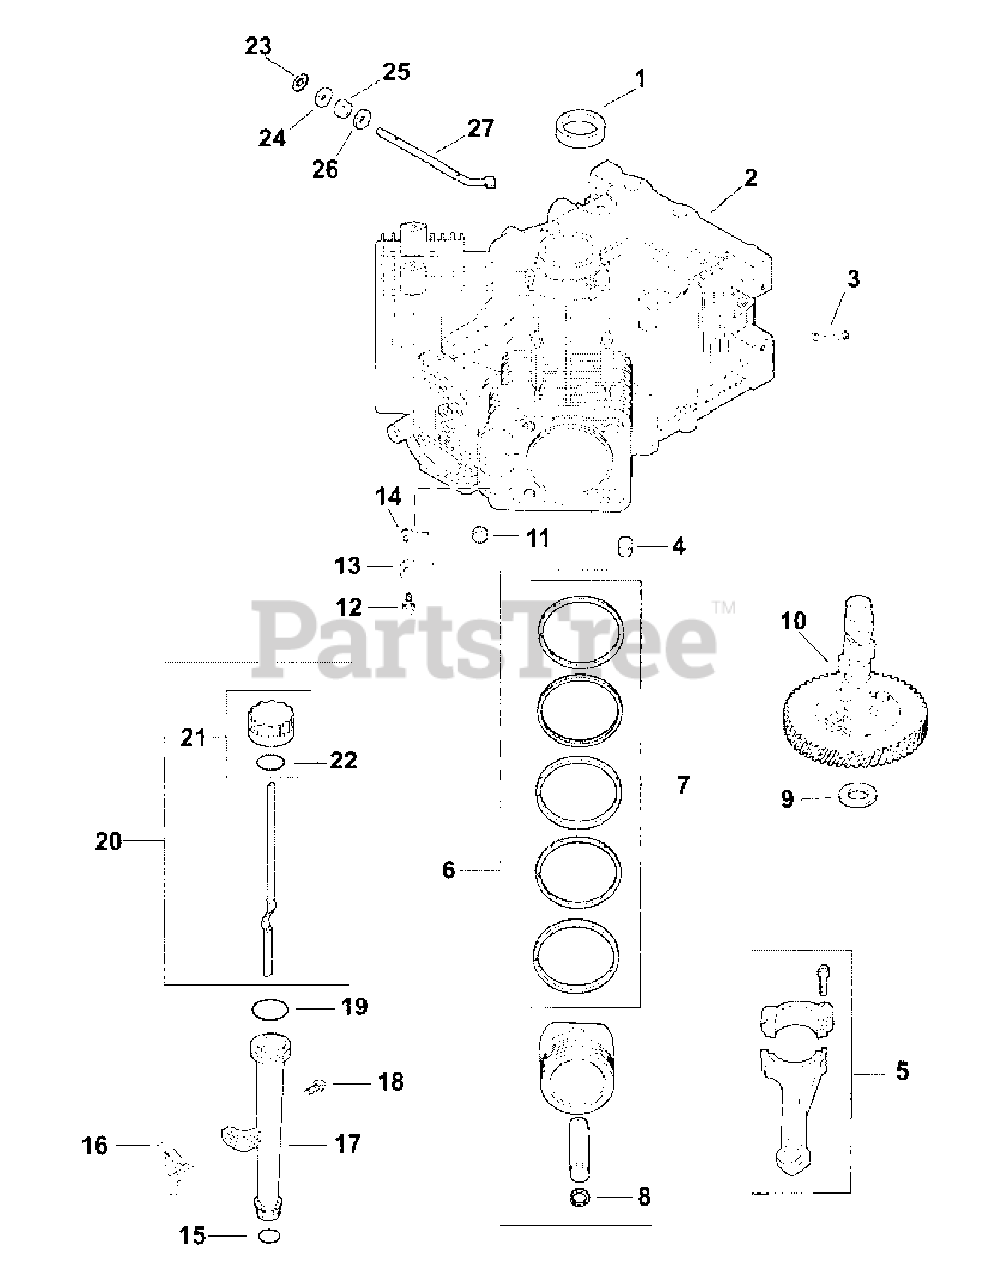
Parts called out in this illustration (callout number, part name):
1	Front Oil Seal
2	Crankcase
5	Connecting Rod (Std.)
5	Connecting Rod (.25)
6	Piston w/Ring Set (Std.)
6	Piston w/Ring Set (.08)
6	Piston w/Ring Set (.25)
6	Piston w/Ring Set (.50)
7	Ring Set (Std. & .08)
7	Ring Set (.25)
7	Ring Set (.50)
8	Piston Pin Retainer
9	Camshaft Shim-Red
9	Camshaft Shim-Black
9	Camshaft Shim-White
9	Camshaft Shim-Blue
9	Camshaft Shim-Yellow
9	Camshaft Shim-Green
9	Camshaft Shim-Gray
10	Camshaft
12	Hex Flange Screw
13	Reed Retainer
14	Breather Reed
15	Lower Oil Fill Tube O-Ring
16	Oil Fill Tube Bracket
17	Oil Fill Tube
18	Hex Flange Screw
19	Upper Oil Fill Tube O-Ring
20	Dipstick Assembly
21	Oil Fill Cap Kit
22	Dipstick O-Ring
23	Ring Retainer
25	Governor Cross Shaft Seal
27	Governor Cross Shaft
